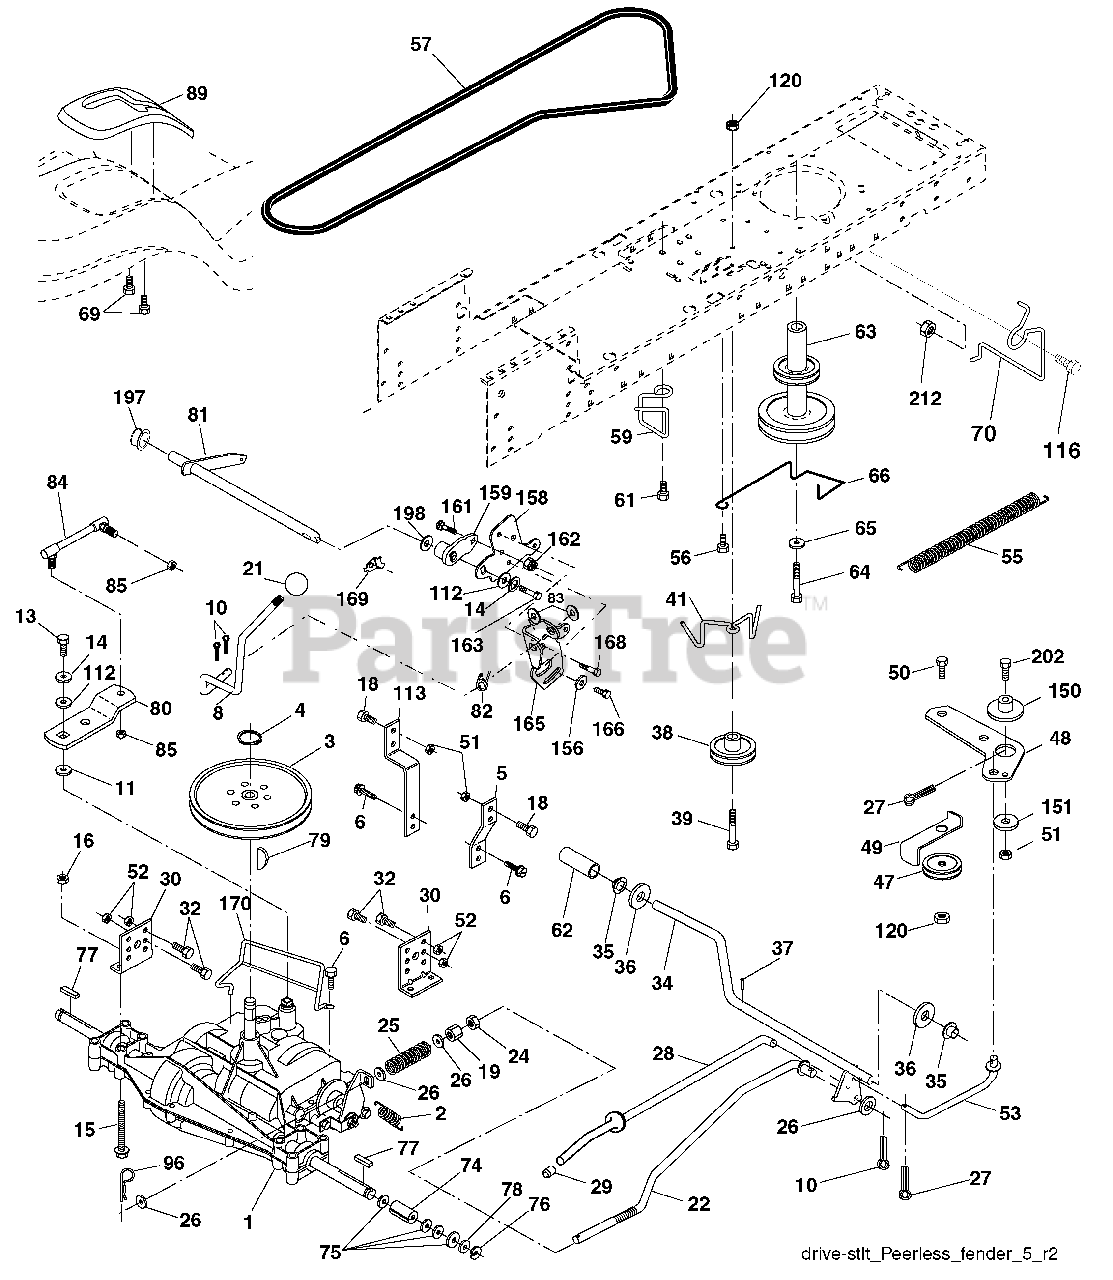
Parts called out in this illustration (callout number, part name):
2	Spring Return Brake T/a Zinc
3	Pulley Transaxle 18” tires
4	Ring Retainer # 5100-62
5	Strap Torque 30 Degrees
6	Screw 5/16-18 x 3/4
8	Rod Shift Fender Adjust Lt
10	Pin Cotter 1/8 x 1 Cad
11	Washer Plate Shf 388 Sq Hole
13	Bolt 1/4-28 Unf Gr 8 W/Patch
14	Washer Lock Hvy Helical
15	Bolt Hex FLGHD 5/16-18 Gr. 5
16	Nut Lock Hex w/ins 5/16-18
18	Bolt, Fin Hex 3/8-16 unc x 1 Gr. 5
19	Nut Lock 3/8-16 unc
21	Knob
22	Rod Brake Blk Zinc 26 840
24	Nut Hex Jam 3/8-16 unc
25	Spring Rod Brake 2 00 Zinc
26	Washer 13/32 x 13/16 x 16 Ga.
27	Pin Cotter 1/8 x 3/4 Cad
28	Rod Brake Parking LT/YT
29	Cap Brake Parking
30	Bracket Mtg Transaxle
32	Bolt Hex Hd 5/16-18unc X 3/4
34	Shaft Asm Pedal Foot
35	Bearing Nylon Blk 629 Id
36	Washer 21/32 x 1 x 16 Ga.
37	Pin Roll 3/16 x 1”
38	Pulley Composite Flat
39	Bolt RDH 3/8-16 unc x 2-3/4 Gr. 5
41	Keeper Belt Flat Idler
47	Pulley Idler V Groove Plastic
48	Bellcrank Asm
49	Retainer Belt Style Spring
50	Bolt Hex Hd 3/8-16 unc x 1-1/2
51	Nut Crownlock 3/8-16 unc
52	Nut Crownlock 5/16-18 unc
53	Link Clutch
55	Spring Return Clutch 6 75
56	Screw 3/8-16 x 1-1/4
57	V-Belt Ground Drive
59	Keeper Belt Span Ctr
61	Screw 3/8-16 x .875
62	Cover Pedal Blk Round
63	Engine Pulley
64	Bolt Hex
65	Washer Lock Hvy Hlcl Spr 7/16
66	Keeper Belt Engine Foolproof
69	Screw Hex wsh HiLo 1/4 x 1/2 unc
70	Guide Belt Mower Drive RH
74	Spacer Axle
75	Washer 25/32 x 1-1/4 x 16 Ga
76	E-ring #5133-75
77	Key Square 2 0 x 1845/1865
78	Washer 25/32 x 1-5/8 x 16 Ga
79	Key Woodruff #9 3/16 x 3/4
80	Arm Shift
81	Shaft Asm Cross Tapered PMST/20
82	Spring Torsion T/a
83	Washer 17/32 x 3/4 x 16 Ga
84	Link Transaxle
85	Nut Lock Center 1/4 - 28 FNTHD
89	Console Shift STLT
96	Retainer Spring 1”
112	Washer 9/32 x 3/4 x 10 Ga.
113	Strap Torque LT
116	Bolt Rdhd Sq Neck 3/8-16 x 1
120	Nut Lock Flg. 3/8-16 unc
150	Spacer Retainer
151	Washer 13/32 x 2 x 10
156	Washer Srrted 5/16ID x 1.125
158	Bracket Shift Mount
159	Hub Shift
161	Bolt Rdhd Sqnk 1/4-20 x 3/4
162	Nut Crownlock 1/4-20 unc
163	Bolt Hex Fin 1/4-20 unc x 1 Gr. 5
165	Bracket Pivot Lever
166	Screw 5/16-18 x 5/8
168	Bolt Shoulder 5/16-18 x .561
169	Plate Fastening
170	Keeper Belt Transaxle Gear
197	Nyliner Snap-In
198	Washer Nyliner
202	Bolt Carr Sh 3/8-16 x 1-3/4 Gr. 5
212	Nut Hex Ange Lock
